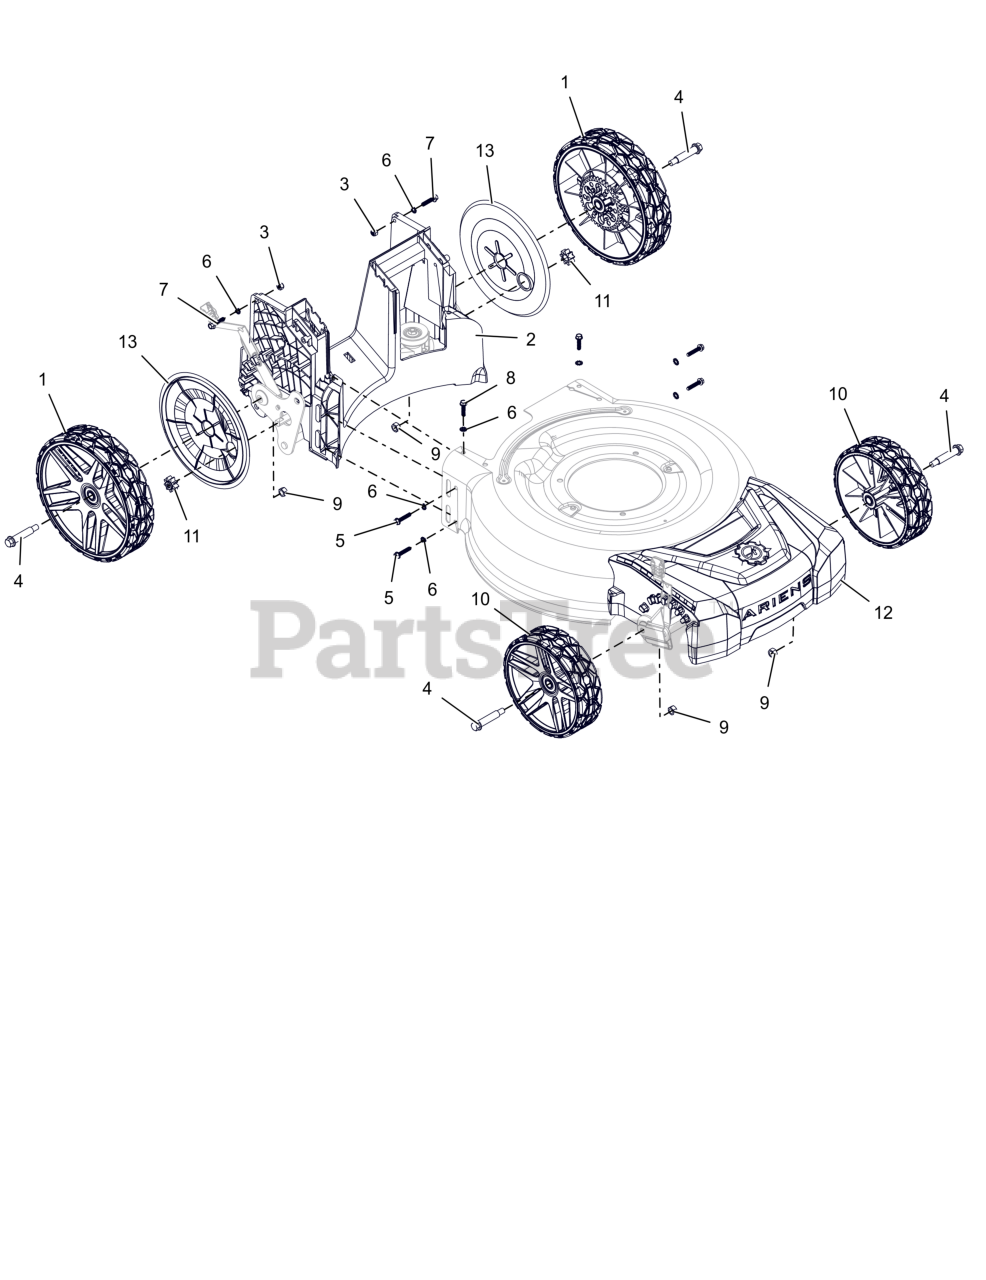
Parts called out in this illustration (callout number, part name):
1	ASM, WHEEL WITH GEAR - 10"
2	BAFFLE, RWD
3	NUT, NYLOC 1/4-20
4	BLT, SHLDR HWH .325X1.981X 3/8-16
5	SCR, HI-LO HWH 1/4-15 X 1.25
6	WSHR-LK-EXT, .256X.510X.028
7	BLT, HEX 1/4-20 X 1.125
8	SCR, HI-LO HWH 1/4-15 X 1.00
9	NUT-JAM .375-16 HIGH STRENGTH
10	WHEEL, 8" - WITH BEARING
11	GEAR, RWD SPUR
12	COVER, FRONT
13	COVER, DUST - 10"
